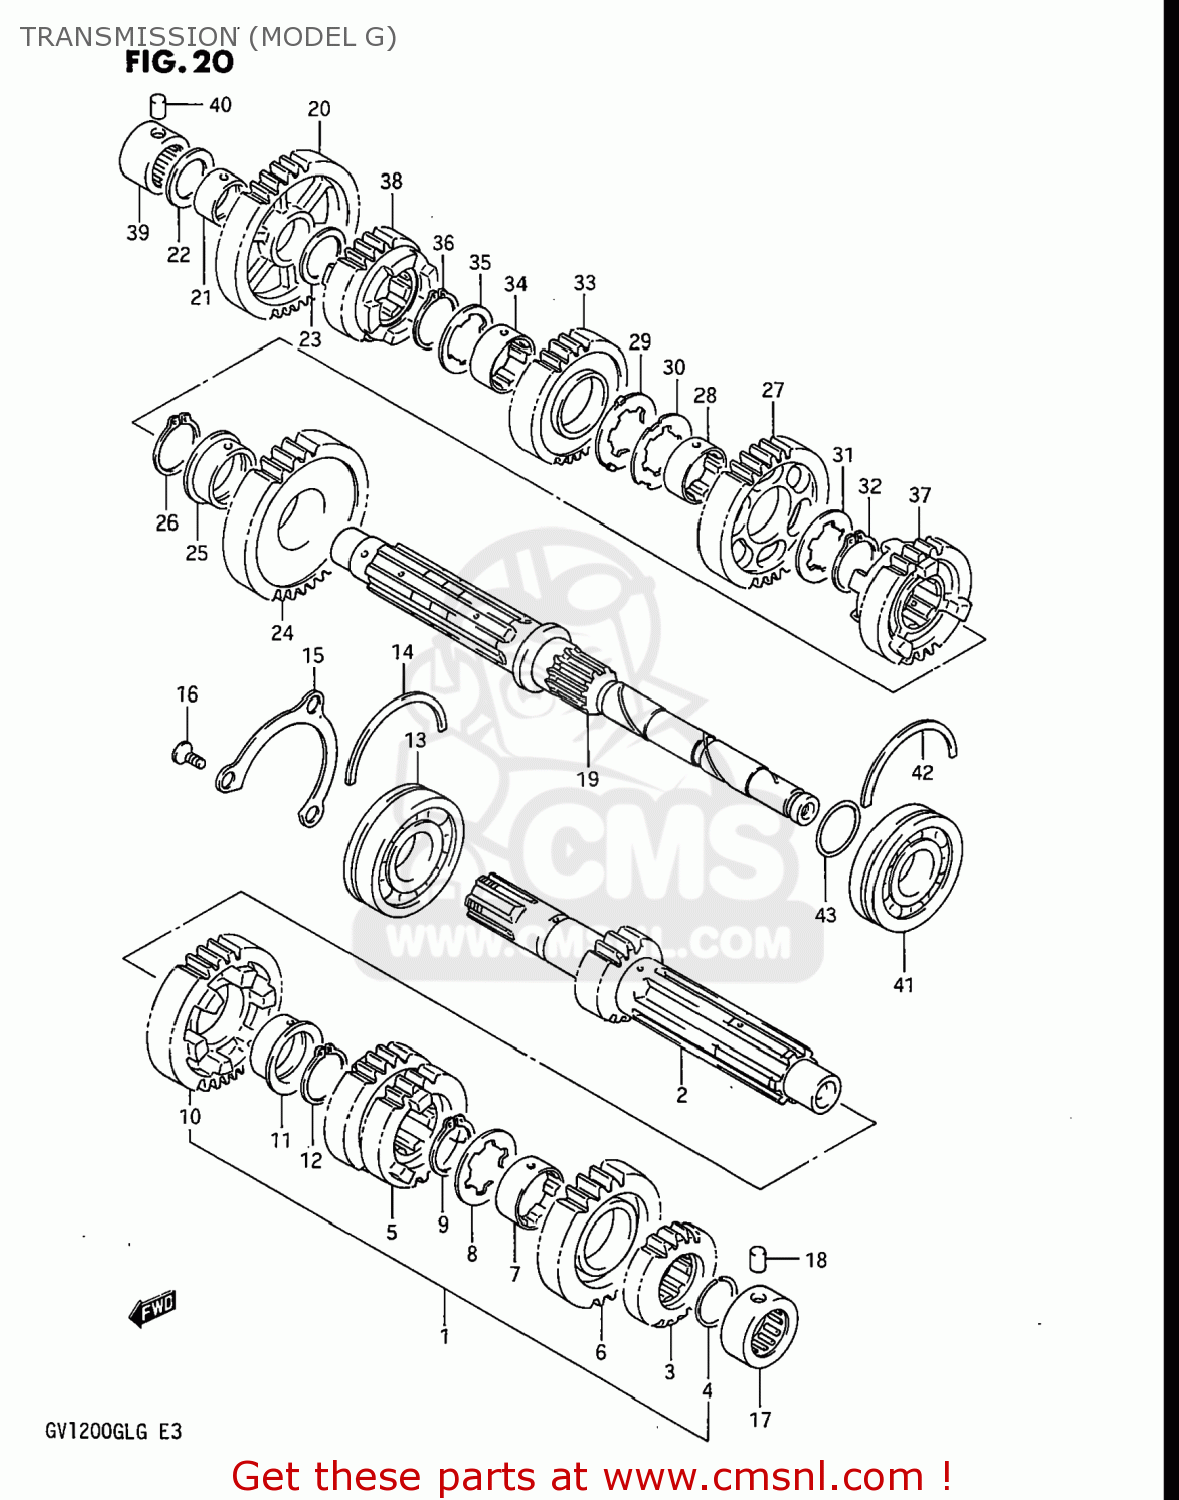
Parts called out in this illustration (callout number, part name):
1	SHAFT,COUNTER
2	COUNTER SHAFT
3	GEAR,SECOND DRIVE
4	CIRCLIP
5	GEAR,THIRD/FOURTH DRIVE
6	GEAR,FIFTH DRIVE
7	BUSH,3RD DRIVEN GEAR
8	WASHER,LOCK
9	CIRCLIP
10	GEAR,SIXTH DRIVE
11	BUSH(28X32X2)
12	CIRCLIP
13	BEARING(25X62X17)
14	C-RING
15	PLATE,COUNTERSHAFT BEARING
16	SCREW
17	ROLLER BEARING (20X36X1
18	PIN
19	SHAFT,DRIVE
20	GEAR,FIRST DRIVEN
21	BUSHING
22	WASHER
23	WASHER
24	GEAR,SECOND DRIVEN
25	BUSH(28X32X2)
26	CIRCLIP
27	GEAR,THIRD DRIVEN
28	BUSH,3RD DRIVEN GEAR
29	WASHER
30	WASHER,LOCK
31	WASHER,LOCK
32	CIRCLIP
33	GEAR,FOURTH DRIVEN
34	BUSH,3RD DRIVEN GEAR
35	WASHER,LOCK
36	CIRCLIP
37	GEAR,FIFTH DRIVEN
38	GEAR,SIXTH DRIVEN
39	BEARING(20X34X20)
40	PIN
41	BALL BEARING 25X62X17
42	C-RING
43	O RING(D:1,ID:24.5)
